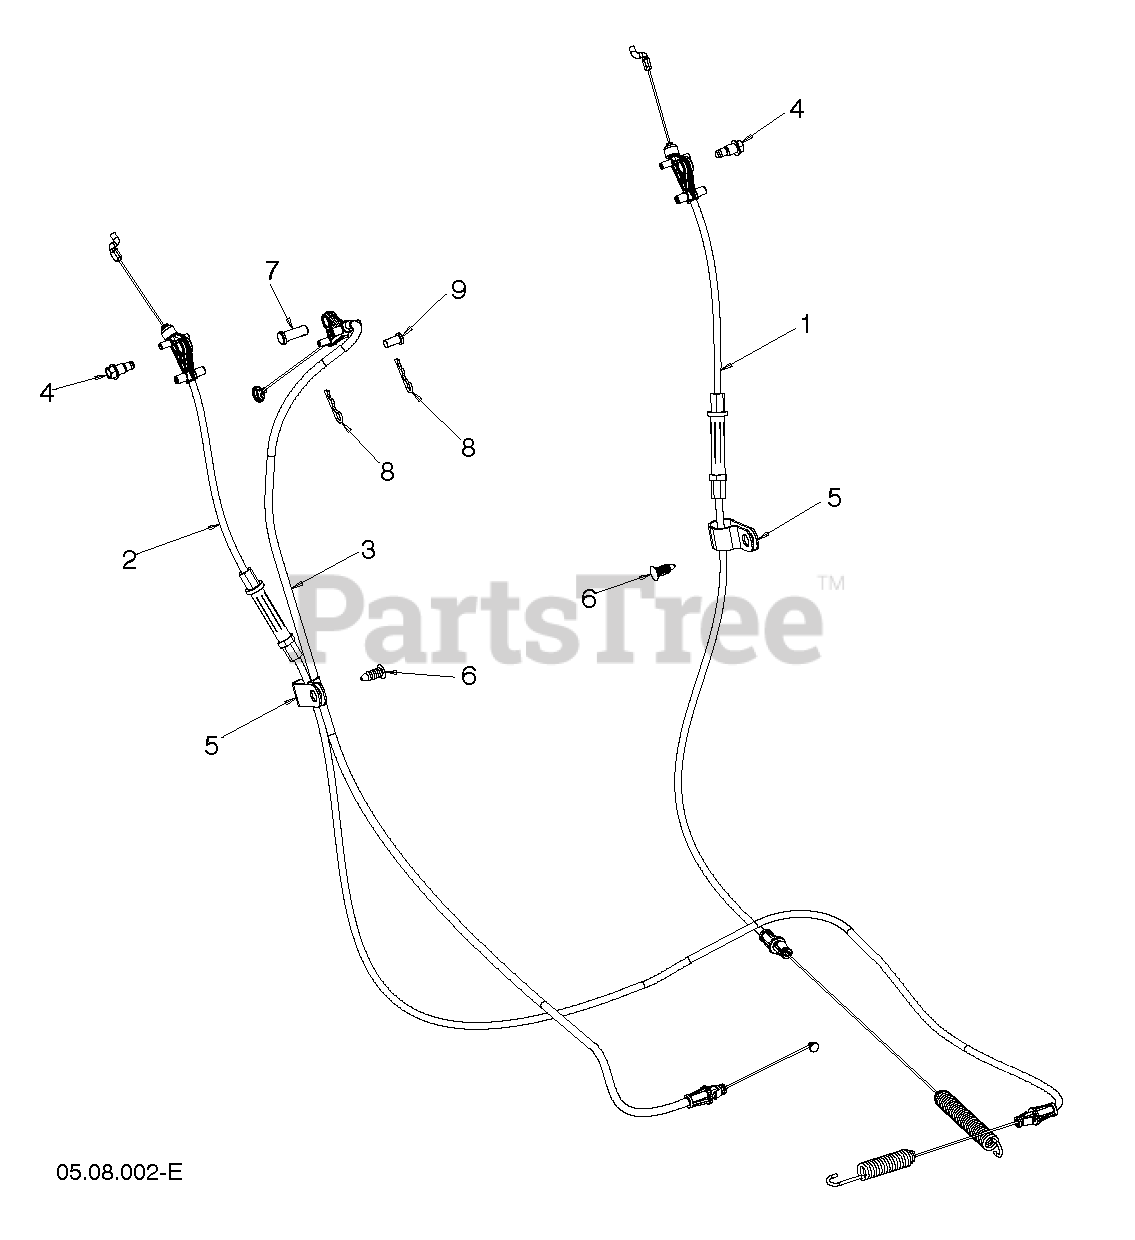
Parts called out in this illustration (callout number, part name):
1	Drive Control Cable, DSST OPP
2	Auger Control Cable, DSST High-Crank
3	Speed Control Cable, DSST OPP
4	Shoulder Bolt, 1/4-20 Trilob
5	CLIP.CABLE.BLK
6	FASTENER.PUSH.O.250X0.783
7	Clevis Pin, 5/16 X .875
9	Clevis Pin, .25 X .31
